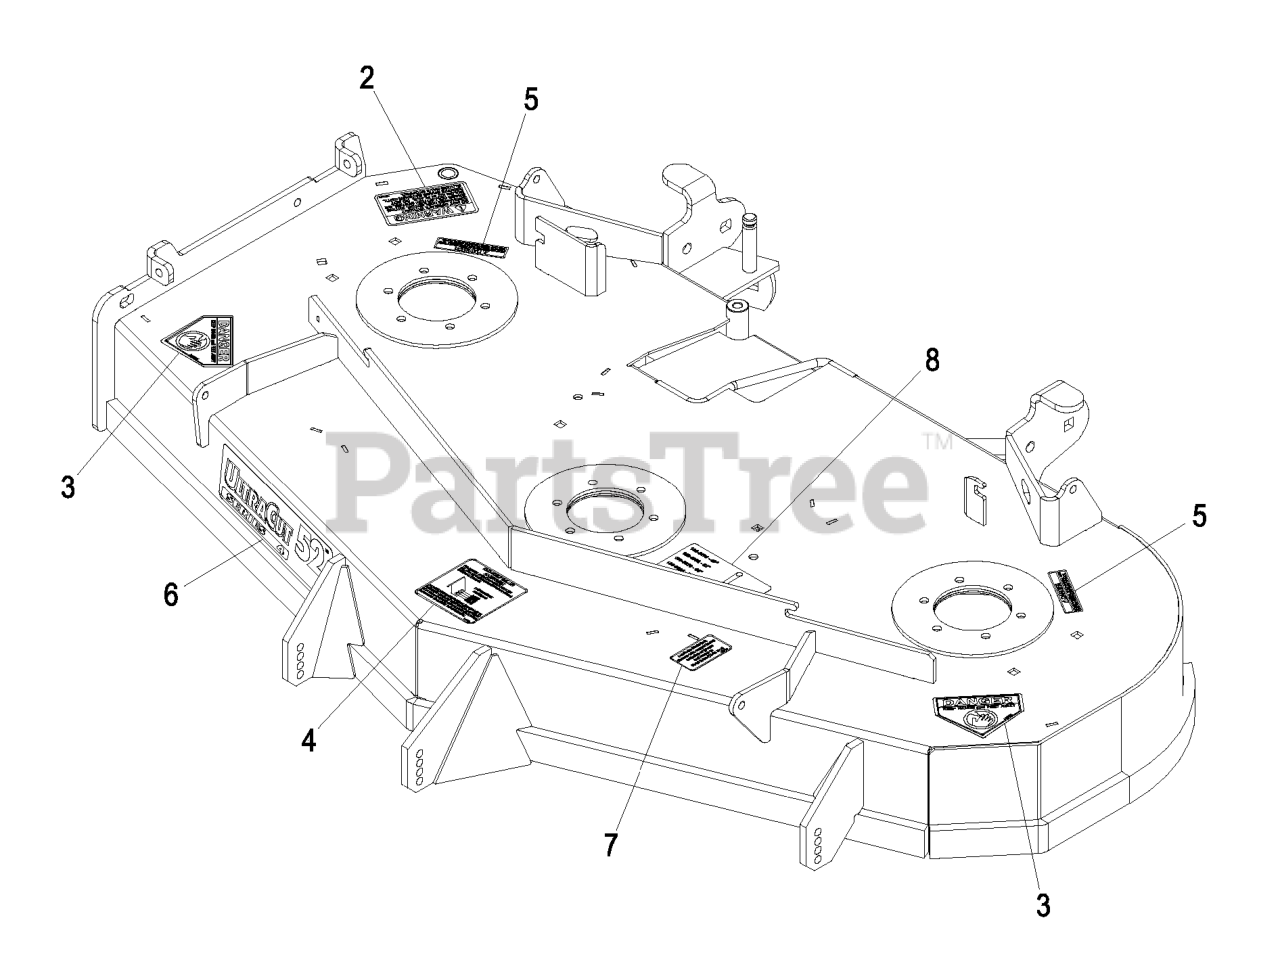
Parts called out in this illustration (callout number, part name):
2	DECAL-WARNING, DISCHARGE
3	DECAL-DANGER
4	DECAL,ANTISCALP
5	DECAL-COVER, MISSING
6	DECAL,ULTRACUT 52 SERIES
7	DECAL,BOLT TORQUE
8	DECAL,BELT ROUTING
